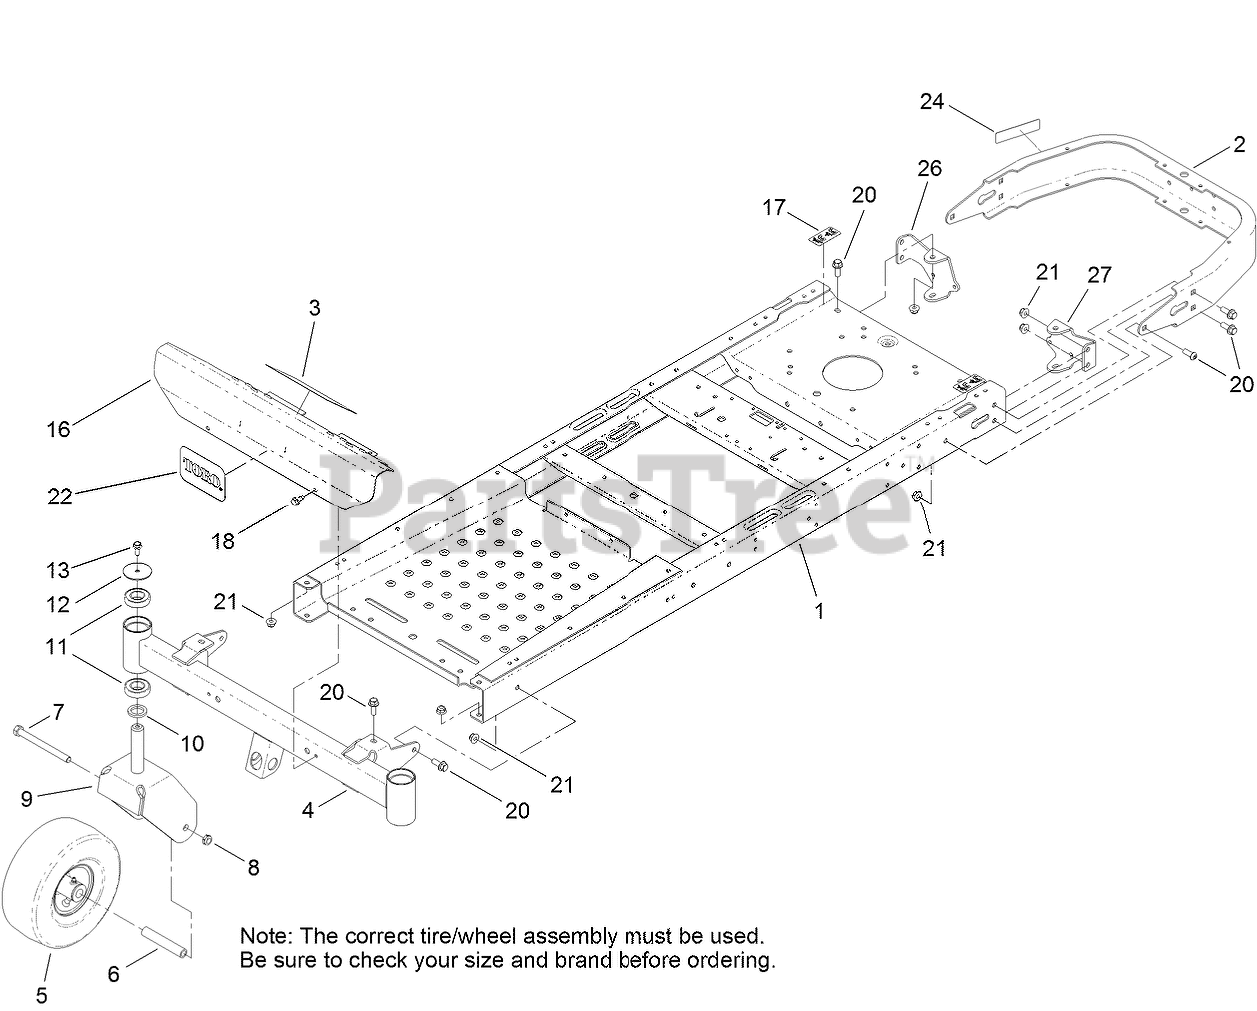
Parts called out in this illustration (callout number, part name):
2	BUMPER-REAR
3	DECAL-DANGER
4	AXLE-FRONT
5	CASTER WHEEL ASM (CST)
5	CASTER WHEEL ASM (Kenda)
6	BUSHING-SPANNER
7	SCREW-HH
8	NUT-LOCK, NI
9	FORK-CASTER
10	WASHER-THRUST
11	BEARING-BALL
12	WASHER
13	SCREW-HHF
16	FOOTREST
17	DECAL-BYPASS
18	SCREW-HWHTF
20	SCREW-HHF
21	NUT-HF, NI
24	DECAL-ARRESTER, SPARK
26	MOUNT-HYDRO, REAR (RH)
27	MOUNT-HYDRO, REAR (LH)
